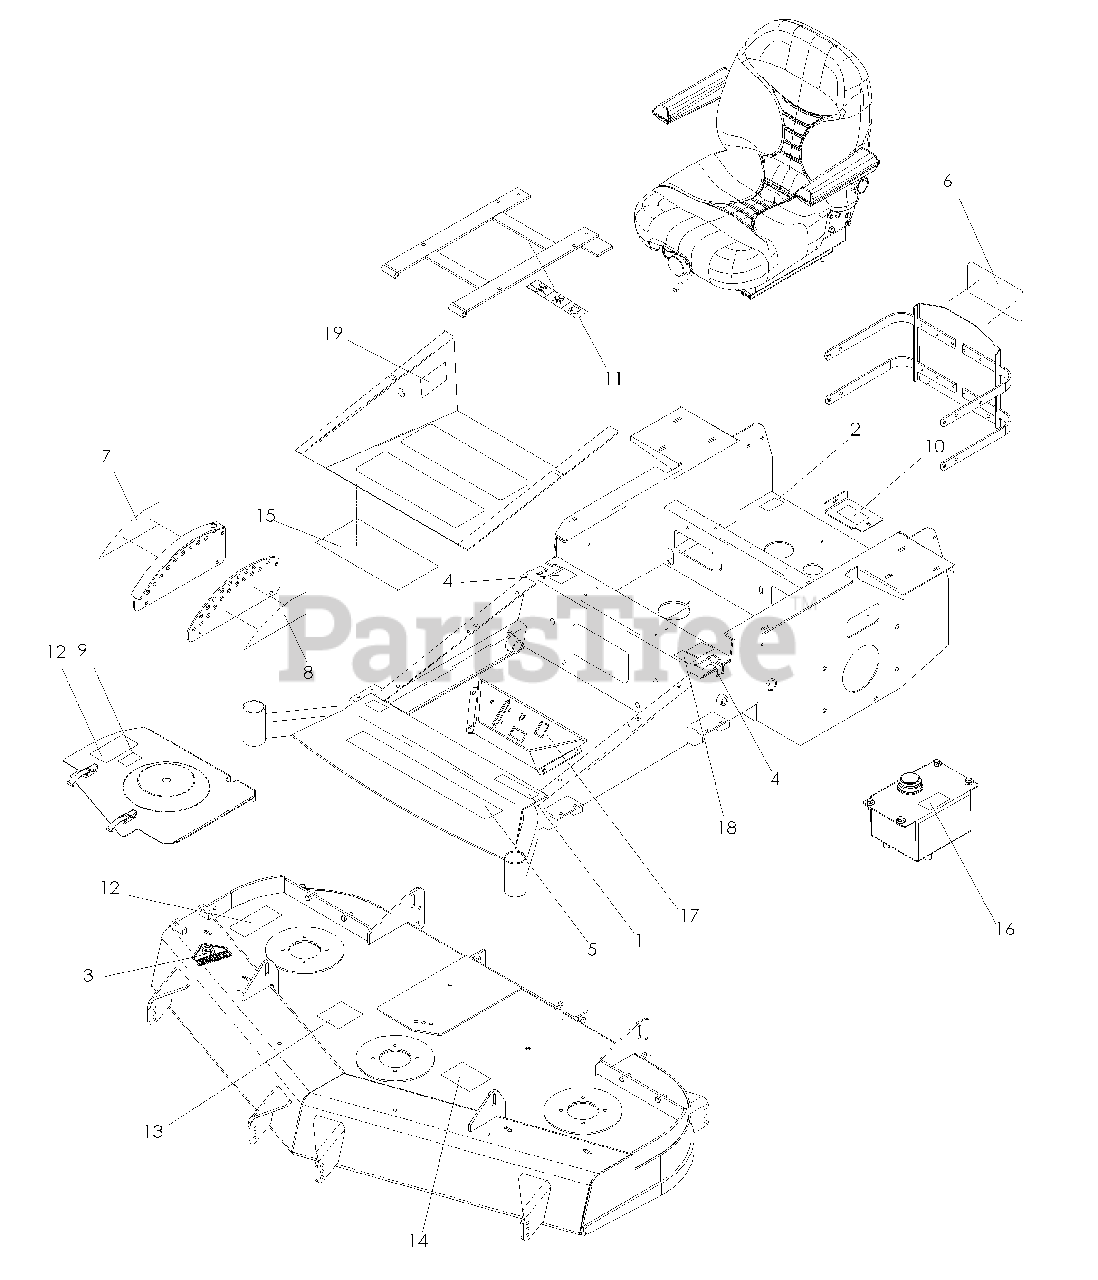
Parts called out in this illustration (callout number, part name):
1	DECAL, LZ5227
1	DECAL, LZ6127
2	DECAL, PROP 65
3	DECAL, WARNING
4	DECAL, MOTION CONTROL
5	DECAL, HUSQVARNA
6	DECAL, HUSQVARNA CRWN
7	DECAL, HEIGHT INDICATOR
8	DECAL, HEIGHT INDICATOR
9	DECAL, NO STEP
10	DECAL, DANGER BELT DR
11	DECAL, BATTERY WARNING
12	DECAL, SEVERING
13	DECAL, ANTI-SCALP
14	DECAL, BELT ROUTING
15	DECAL, SERVICE
16	DECAL, OIL TANK
17	DECAL, CONSOLE
18	DECAL, TRACKING
19	DECAL, WARNING
